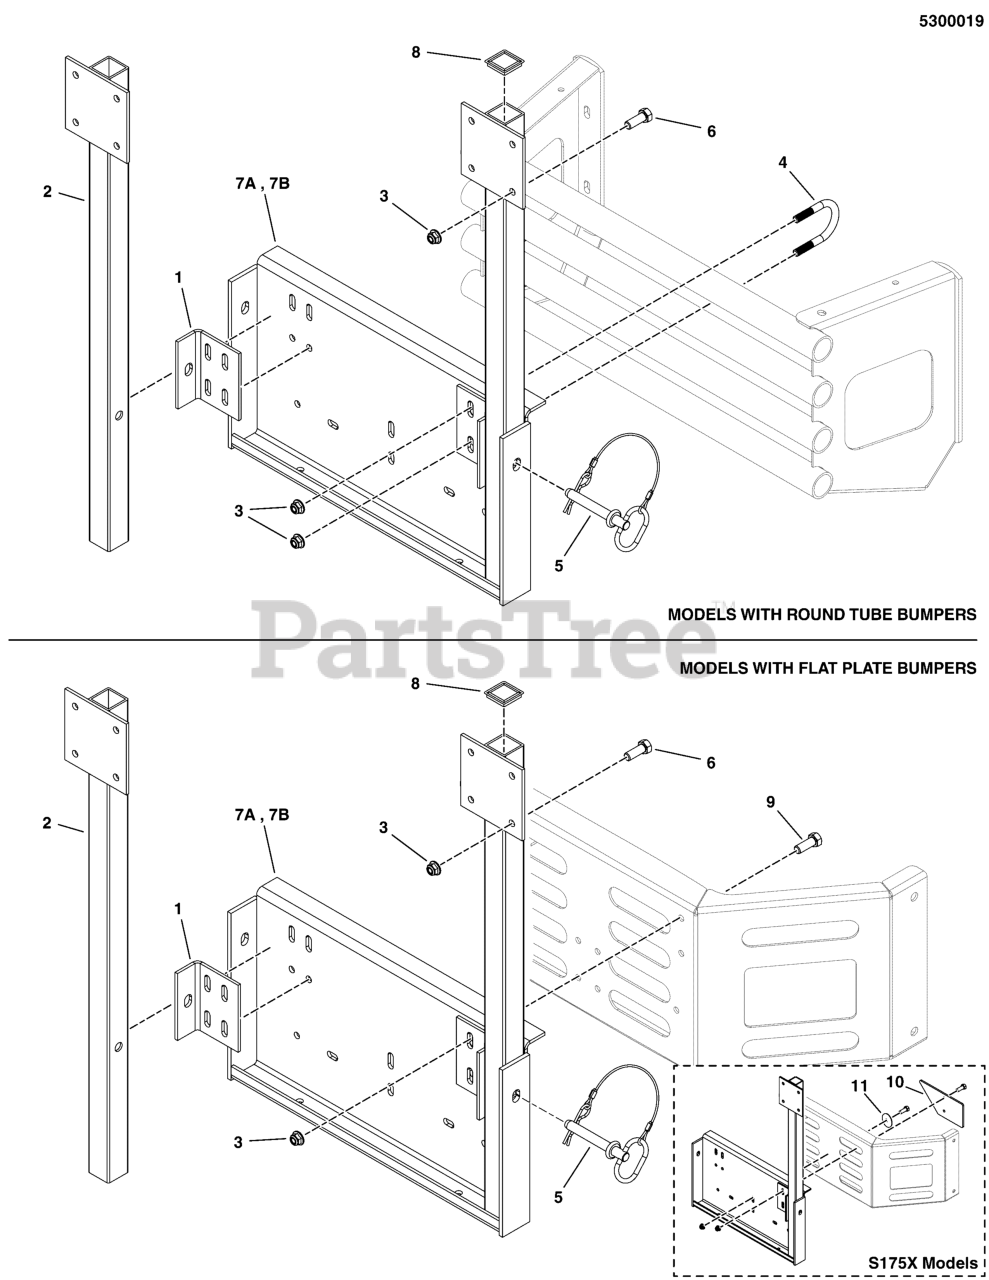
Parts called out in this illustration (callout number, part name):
1	MOUNT, TAB, BLACK
2	WELD, MOUNT, POST - BLK
3	NUT, 3/8-16 HEX NYLOCK FLANGE
4	U-BOLT, 3/8 X 1-1/4
5	PIN, HITCH, .50 X 3.25 W/ LAY
6	BOLT, 3/8-16 X 1" GD5 CZ
7A	WELD, BAGGER MOUNT, 2 BAG - BLK
7B	WELD, 3-BAG MOUNT, ALL - BLK
8	CAP, PLASTIC, 1-1/2" X 1-1/2
9	BOLT, 3/8-16 X 1-1/4" GD5 CZ
10	PLATE, SUPPORT, BAGGER MOUNT - BLK
11	WASHER, .39 X 2.00 X X .14
